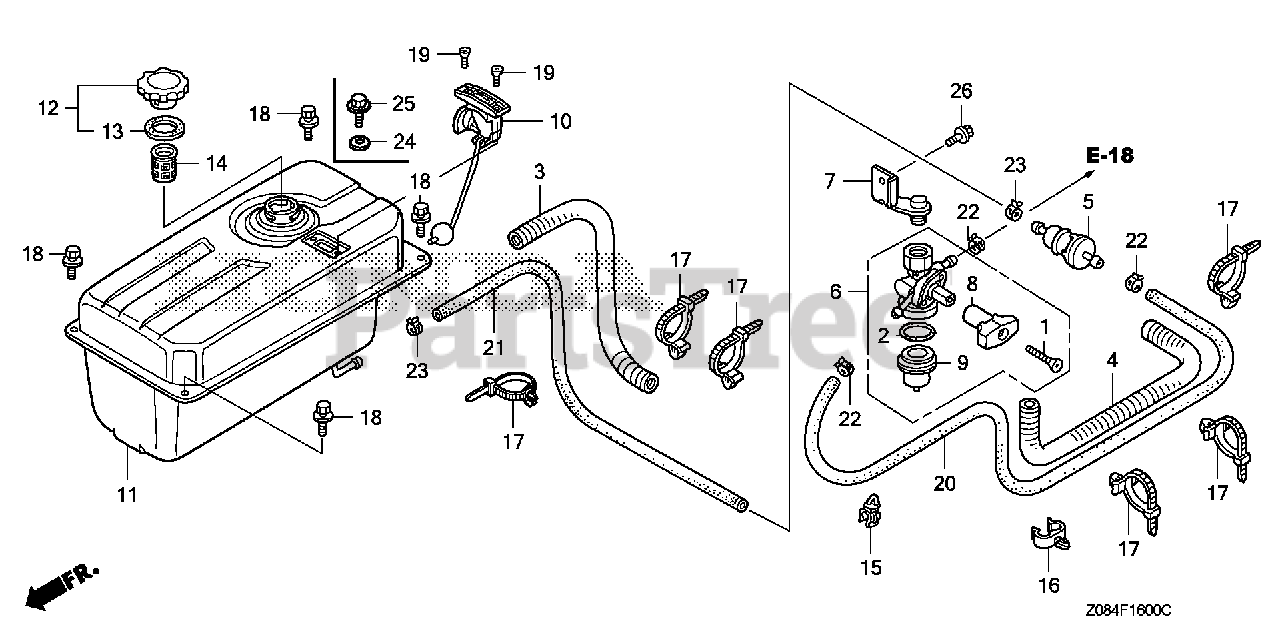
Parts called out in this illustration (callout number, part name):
1	SCREW, OVAL (4X32)
2	GASKET, FUEL STRAINER CUP
3	PROTECTOR, TUBE (A)
4	PROTECTOR, TUBE (B)
5	FILTER, FUEL
6	PETCOCK ASSY.
7	STAY, PETCOCK
8	LEVER, PETCOCK
9	CUP, FUEL STRAINER
10	METER ASSY., FUEL
11	TANK, FUEL *R280* (POWER RED)
12	CAP, FUEL FILLER
13	GASKET, FUEL FILLER CAP
14	FILTER, FUEL
15	CLIP, THROTTLE WIRE
16	CLAMP, IGNITION WIRE
17	BAND, WIRE HARNESS (150MM) (NATURAL)
18	BOLT-WASHER (6X16)
19	SCREW, FLAT (5X10)
20	BULK HOSE, FUEL (4.5X3000) (4.5X800)
21	BULK HOSE, FUEL (5.5X3000) (5.5X700)
22	CLAMP, TUBE (D8.5)
23	CLAMP, TUBE (D10.5)
24	WASHER, PLAIN (6MM)
25	BOLT, FLANGE (6X16)
26	BOLT, FLANGE (6X12)
